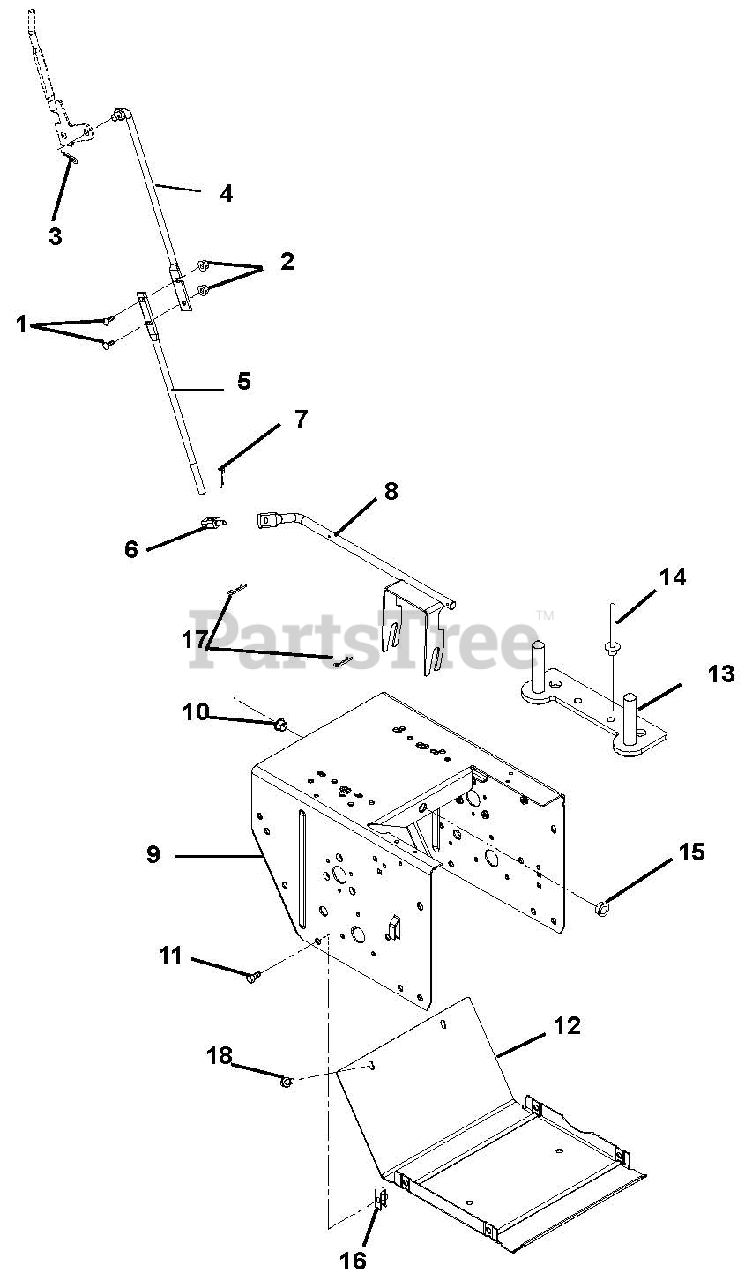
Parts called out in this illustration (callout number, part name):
1	@BLT-RDHDSQNK .25-20X.75 G5YZ
2	@NUT-LK-TOP-FLG .25-20 YWZC
3	PIN-HAIR, ENDRIES #25 YWZC
4	ROD, SHIFT-UPPER
5	ROD, SHIFT-LOWER
6	PIVOT,SHIFT ROD .375-16(TRUNN)
7	PIN-HAIR, ENDRIES #25 YWZC
8	ARM, SHIFT-WELDMENT
9	FRAME, MAIN
10	BUSHING, POLYLINER-.50 SPLIT
11	BLT-HEX .25-20X.75 HWH YZ GR5
12	COVER, BOTTOM
13	STRAP, ENGINE BOLT-LARGE BRIGG
14	RVT-POP .187 YZ
15	BUSHING, POLYLINER-.50 SNAPIN
16	NUT-RTNR .25-20X.56
17	CLIP, SPRING
18	SCR-TAP .25-20X.50 HWH TR YWZ
